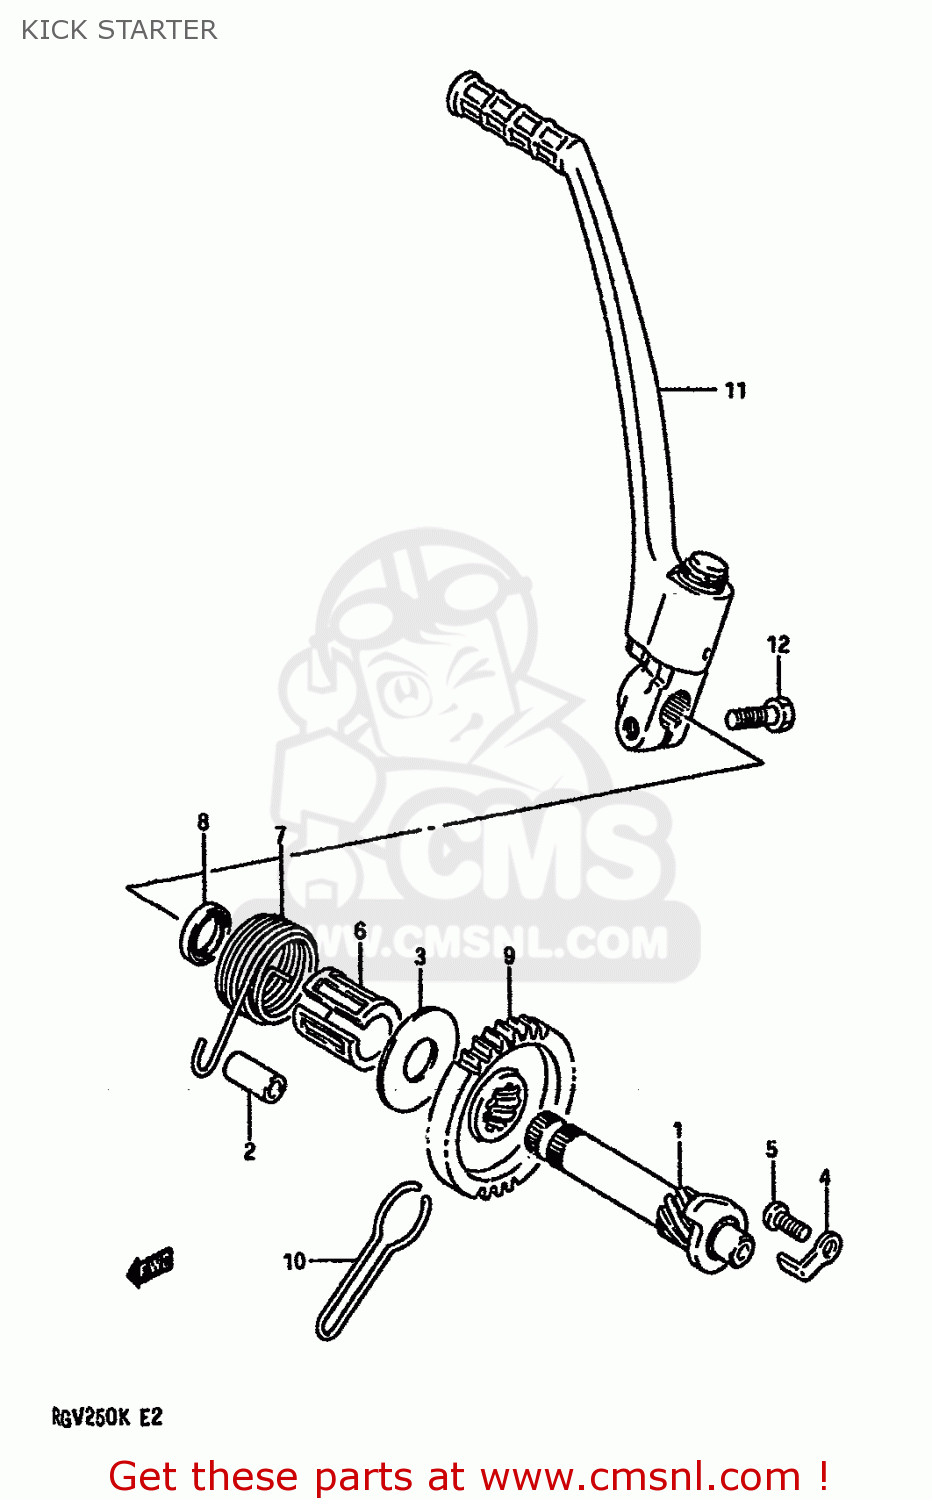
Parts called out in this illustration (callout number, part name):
1	SHAFT,KICK STARTER
2	SPACER (6.5X10.5X22.5)
3	WASHER
4	STOPPER, KICK STARTER
5	SCREW
6	GUIDE,KICK STARTER SFT SPRING
7	SPRING
8	SEAL,OIL(16X24X5)
9	GEAR,KICK DRIV
10	SPRING,RETAINER
11	LEVER ASSY,KICK STARTER
12	BOLT
